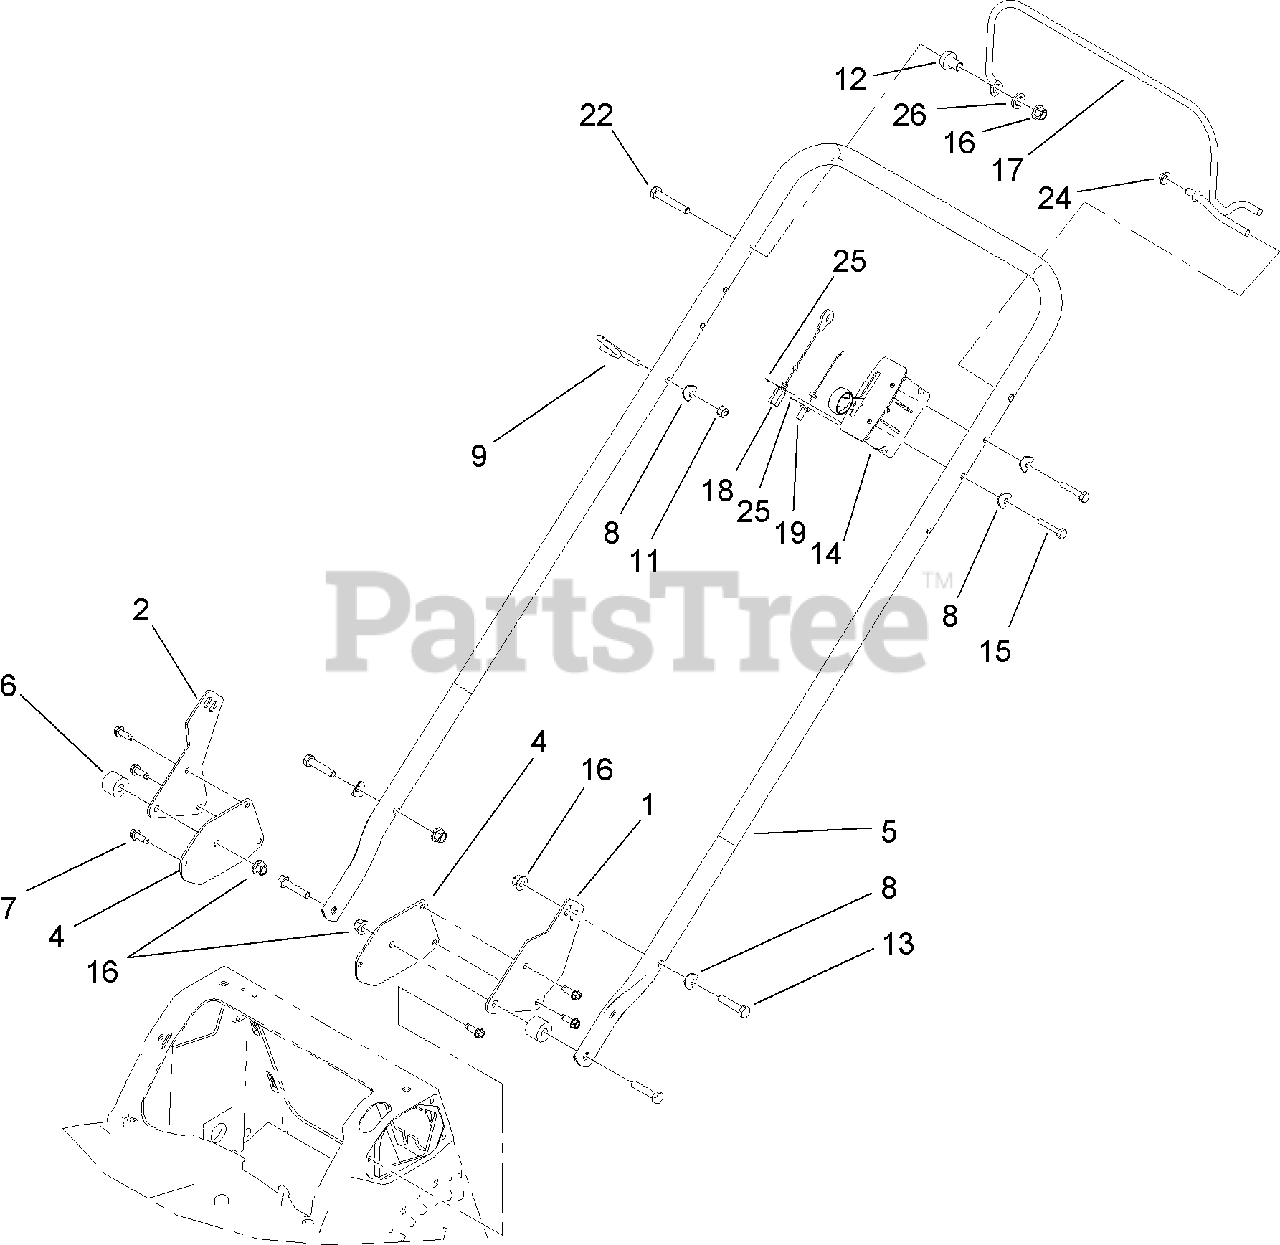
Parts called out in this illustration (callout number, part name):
1	SUPPORT-STRUT, LH
2	SUPPORT-STRUT, RH
4	PLATE-HANDLE
5	HANDLE
7	SCREW-HWHTF
9	GUIDE-ROPE
11	NUT-LOCK, NI
12	SPACER-SUPPORT
13	SCREW-HH
14	CONTROL-HEAD, THROTTLE
15	SCREW-HH
16	NUT-LOCK, NI
18	CABLE-BRAKE
19	THROTTLE CABLE ASM
22	SCREW-HH
24	NUT-PUSH
